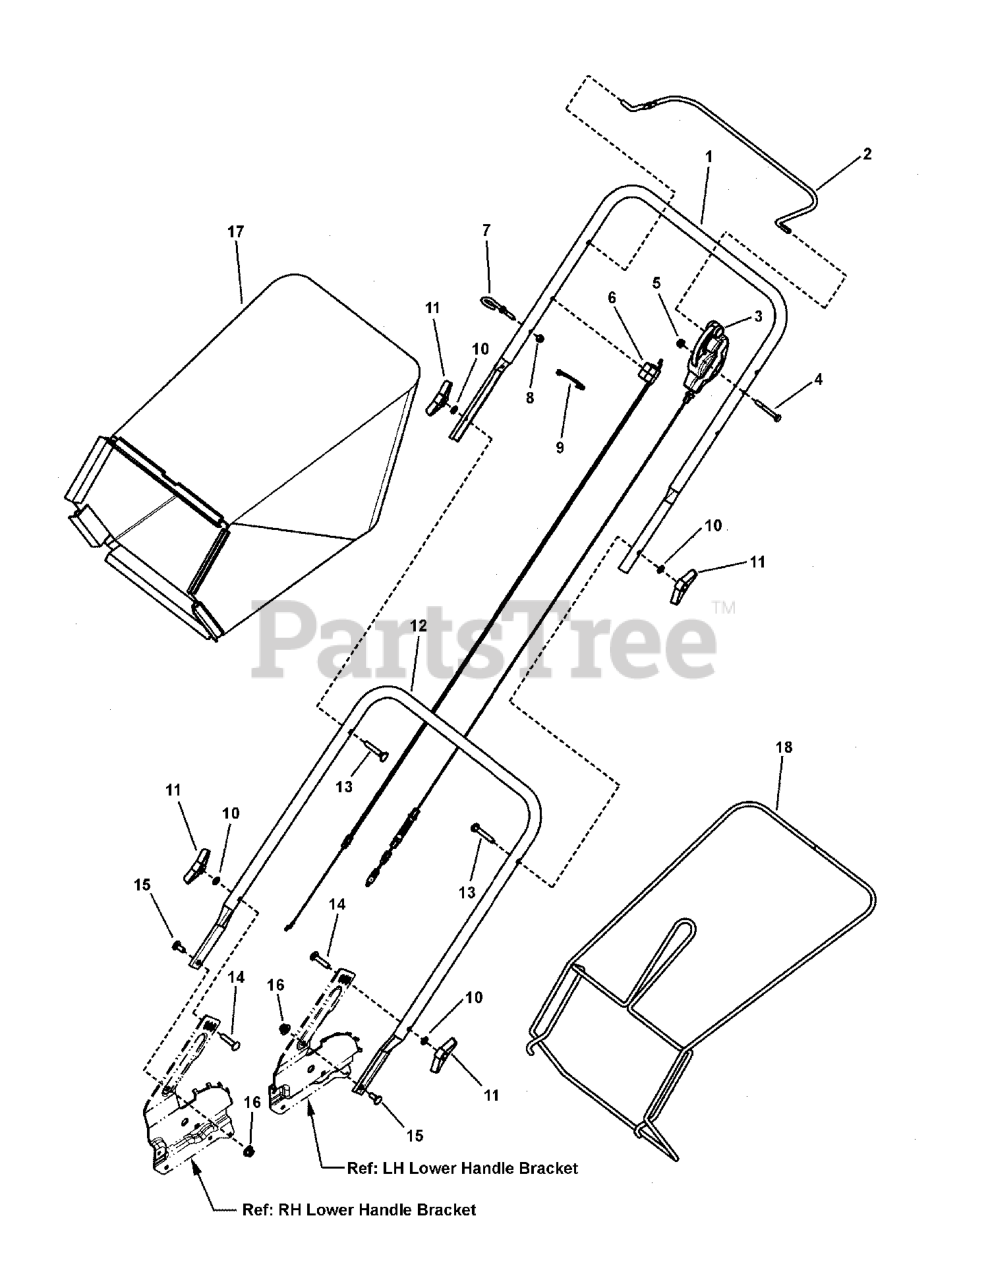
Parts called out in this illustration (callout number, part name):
1	UPPER HANDLE
2	BAIL, OPC Propelled
3	CONTROL, Drive, Single Speed
4	SCREW, 1/4-20 x 2-1/4" Hex Head Cap, GR 5
5	NUT, 1/4-20 Hex Flange Esna, YZ
6	CABLE, Bail, 22" Brute WBM
7	ROPE GUIDE (1/4-20 thread)
8	NUT, 1/4-20 Nyloc
9	WIRE TIE,11 Inch Std Black Nylon
10	WASHER, 5/16" Internal Tooth lock
11	KNOB, 5/16-18 Wing Nut
12	HANDLE, Lower, 21" Rear Discharge
13	BOLT, 5/16-18 x 2" Curved Head Square Neck, GR 2
14	BOLT, 5/16-18 x 1-1/2" Round Head Short Square Neck Carriage, GR 5
15	BOLT, 5/16-18 x 3/4" Round Head Short Square Neck Carriage, YZ
16	NUT, 5/16-18 Large Head Center Lock
17	BAG, Grass, 22" Rear Discharge
18	BAG FRAME, Rear Discharge
